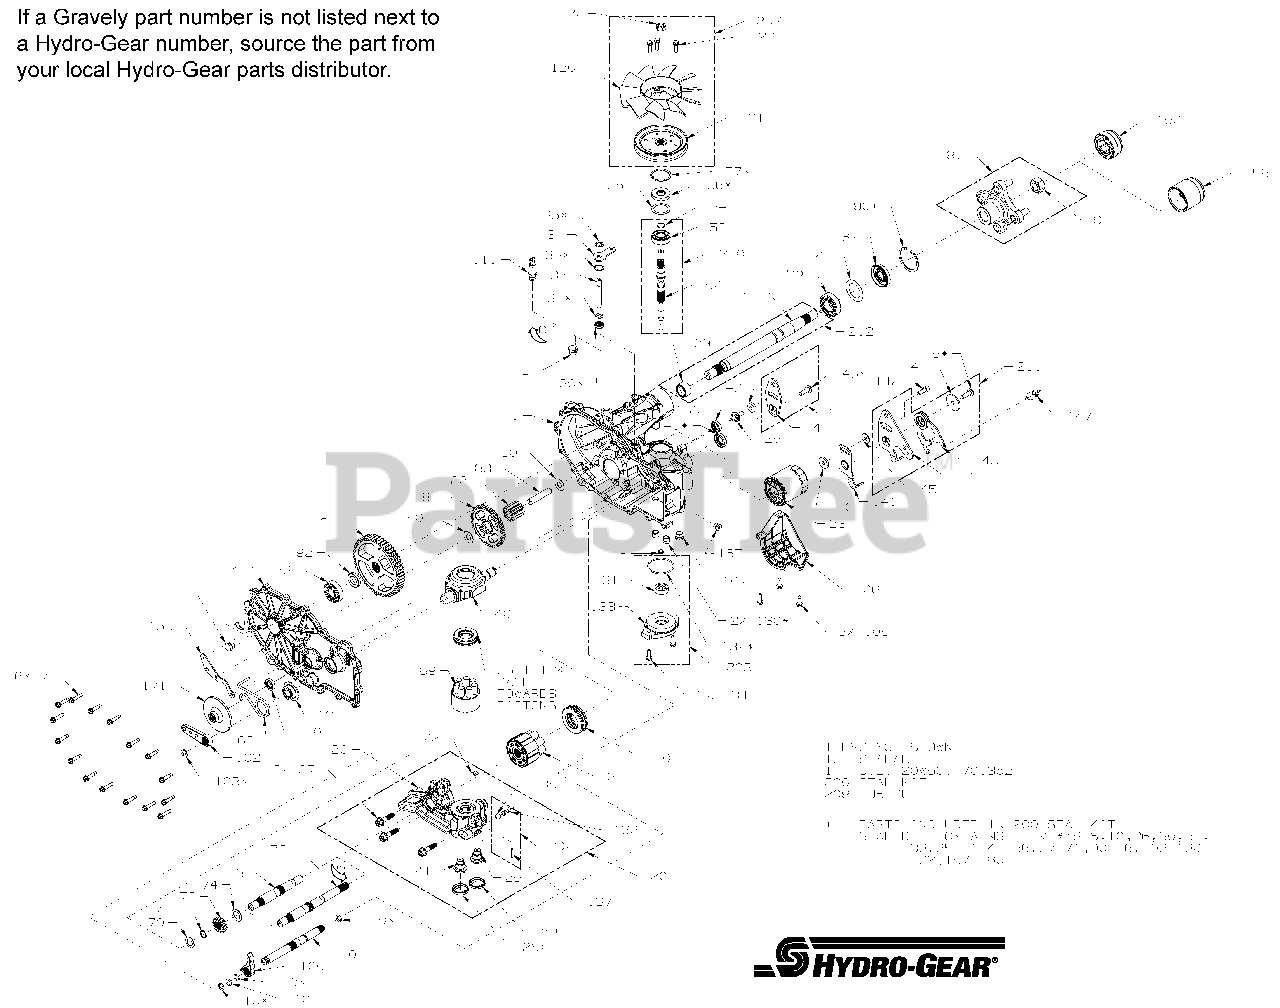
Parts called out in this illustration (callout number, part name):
7	HFHCS 1/4-20 x 1.125"
13	SEALANT, TUBE
22	PLATE, BYPASS
23	FILTER, OIL
26	SEAL, PLUG 1.250 X .250
30	SEAL, LIP .375 X .75 X .25
31	RING, RETAINING .375 EXTERNAL
33	RING, RETAINING .750 INTERNAL
34	ARM, BYPASS
35	RING, RETAINING .375 EXTERNAL
40	TRUNNION, SWASHPLATE
41	SEAL, LIP 12 X 32 X 7
45	WASHER, .34 X .88 X .06
46	TWHCS 5/16-24 X 1.00
55	WASHER, 1.23 X 1.56 X .04
56	SEAL, LIP 17 X 40 X 7
57	RING, RETAINING
60	BEARING, THRUST
64	KIT, 16cc MOTOR BLOCK
65	BEARING, THRUST BALL 30 X 52 X 13
69	ASS'Y, BLOCK 7 PISTON
70	WASHER, .63 X 1.0 X .05
71	RING, RETAINING .625
74	WASHER, .72 X 1.16 X .04
80	WASHER, .5 X 1.0 X .03
83	JACK SHAFT
90	RING, RETAINING 2.06 INTERNAL
95	BEARING, BALL 1.0 X 52 X 15 OPEN 6205M
96	SEAL, LIP TC4, 1.0 X 2.06 X .38
97	KIT, HUB, 5 BOLT
99	NUT, HEX LOCK 3/4-16
102	KIT, BRAKE ARM LEFT HAND
105	HFHCS 1/4-20 X .75
106	GUARD, FILTER, LH
111	FITTING, STR 9/16-18 SAE .5 BARB
122	NUT, HEX JAM 1/2-20 W/ PATCH
131	GEROTOR ASSEMBLY
132	O-RING, -.137, .103 X 2.050
134	HFHCS 1/4-20 X .75
140	SPACER, .320 X 1.005 X .179
141	ARM, NEUTRAL LEFT
142	SHCS 5/16-24 X 1
200	KIT, SEAL
201	KIT, CENTERSECTION, LH, CHRG
203	KIT, CHARGE PUMP
207	KIT, FAN/PULLEY
209	HUB PULLER, UNIVERSAL
210	KIT, INPUT SHAFT
211	KIT, RTN, CCW
